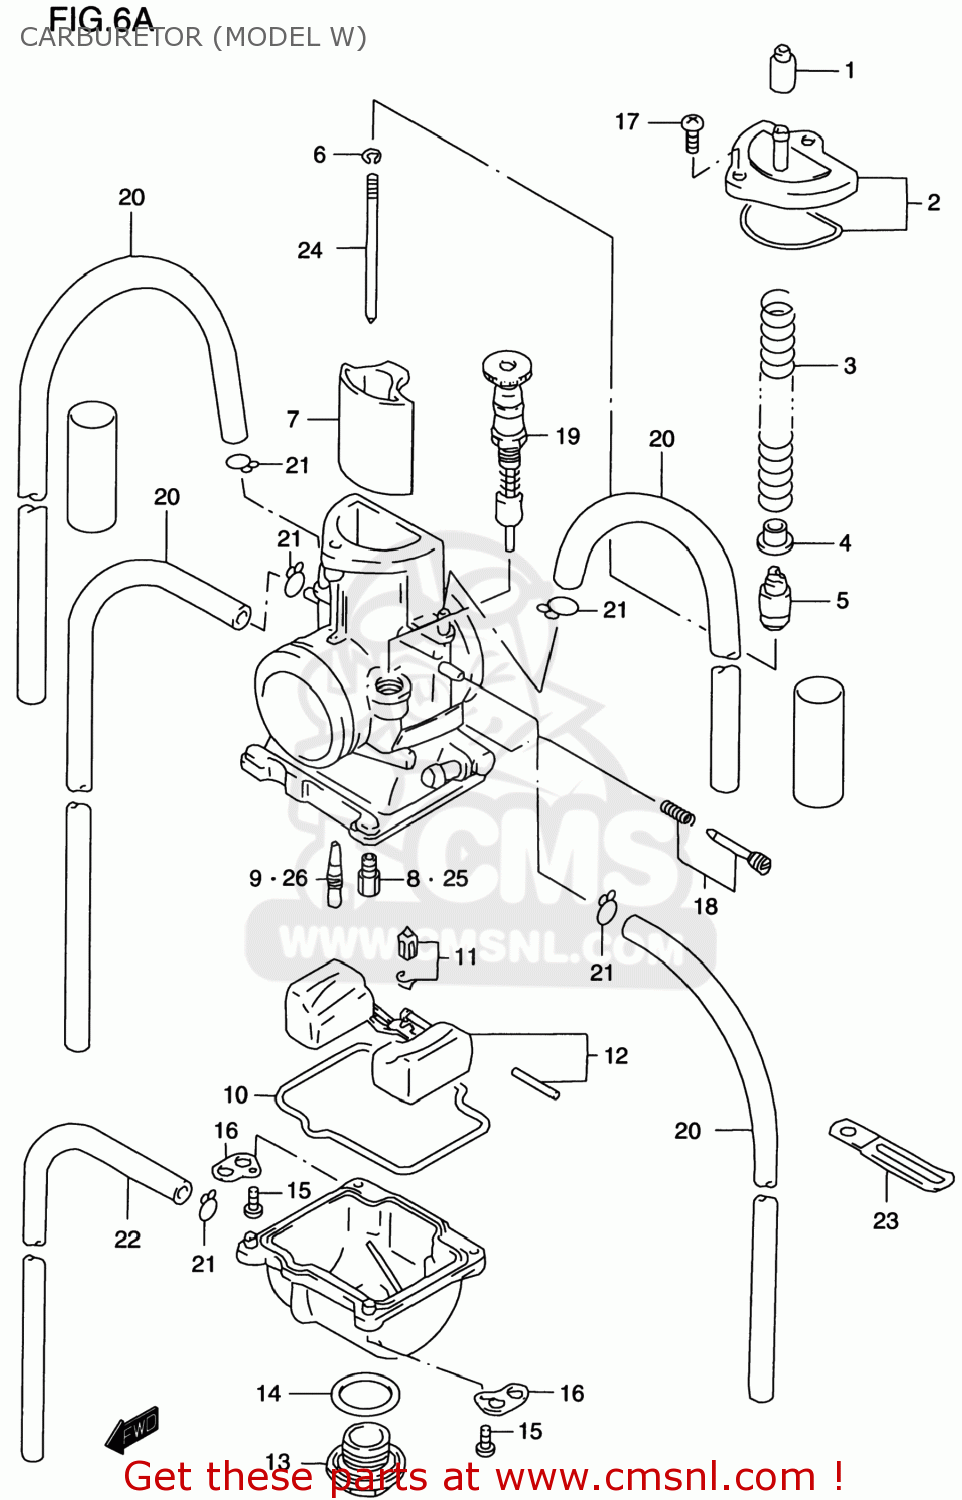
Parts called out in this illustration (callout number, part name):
1	CAP,CARBURETOR
2	CAP SET,TOP
3	SPRING,THROTTLE VALVE
4	COLLAR,THROTTLE VALVE
5	HOLDER,CABLE
6	CLIP,NEEDLE
7	VALVE,THROTTLE
8	JET,MAIN(175)
9	JET,SLOW(55)
10	GASKET,FLOAT CHAMBER
11	VALVE SET,FLOAT
12	FLOAT SET
13	BOLT,DRAIN
14	O RING
15	SCREW
16	PLATE
17	SCREW
18	SCREW SET,AIR
19	STARTER VALVE
20	HOSE(4X7X620)
21	CLIP
22	HOSE(3.5X6.5X600)
23	CLAMP(L:45)
24	NEEDLE(R1469MS)
25	JET,MAIN(145)
26	JET,SLOW(35)
